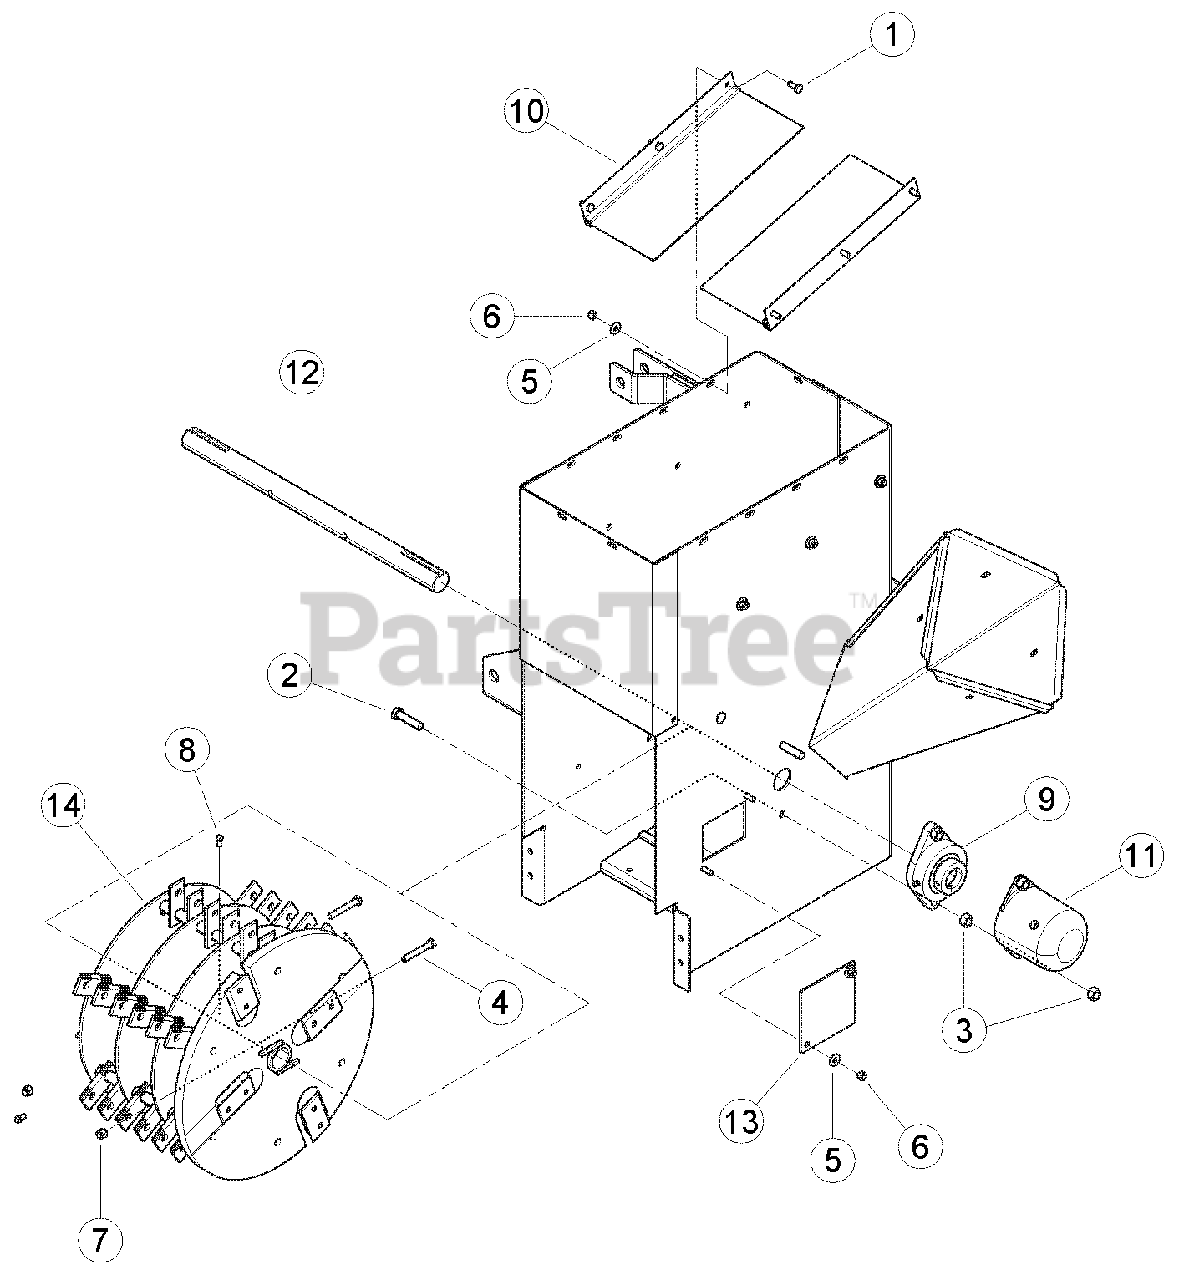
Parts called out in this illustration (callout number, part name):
1	BOLT, 5/16 X 3/4 HEX HD GR5 ZP
2	BOLT, 1/2 X 2 HEX HD GR5 ZP
3	NUT, 1/2 CENTERLOCK GRB ZP
4	BOLT, 3/8 X 2-1/2 HEX HD GR5 ZP
5	WASHER, 5/16 FLAT ZP
6	NUT, 5/16 NE NYLOCK ZP
7	NUT, 3/8 NE NYLOCK ZP
8	SET SCREW, 5/16-18 X 1/2 SQ HD,CUP
9	BEARING, 2 BOLT FLANGE 1-1/2" BORE
10	BRUSH, INLET
11	CAP, LARGE SHAFT
12	SHAFT, LARGE C/S ROTOR
13	COVER, BLADE ACCESS
14	ASSY, COMM ROTOR W/RECT KNIVES (SEE PAGE 14 FOR DETAILS)
